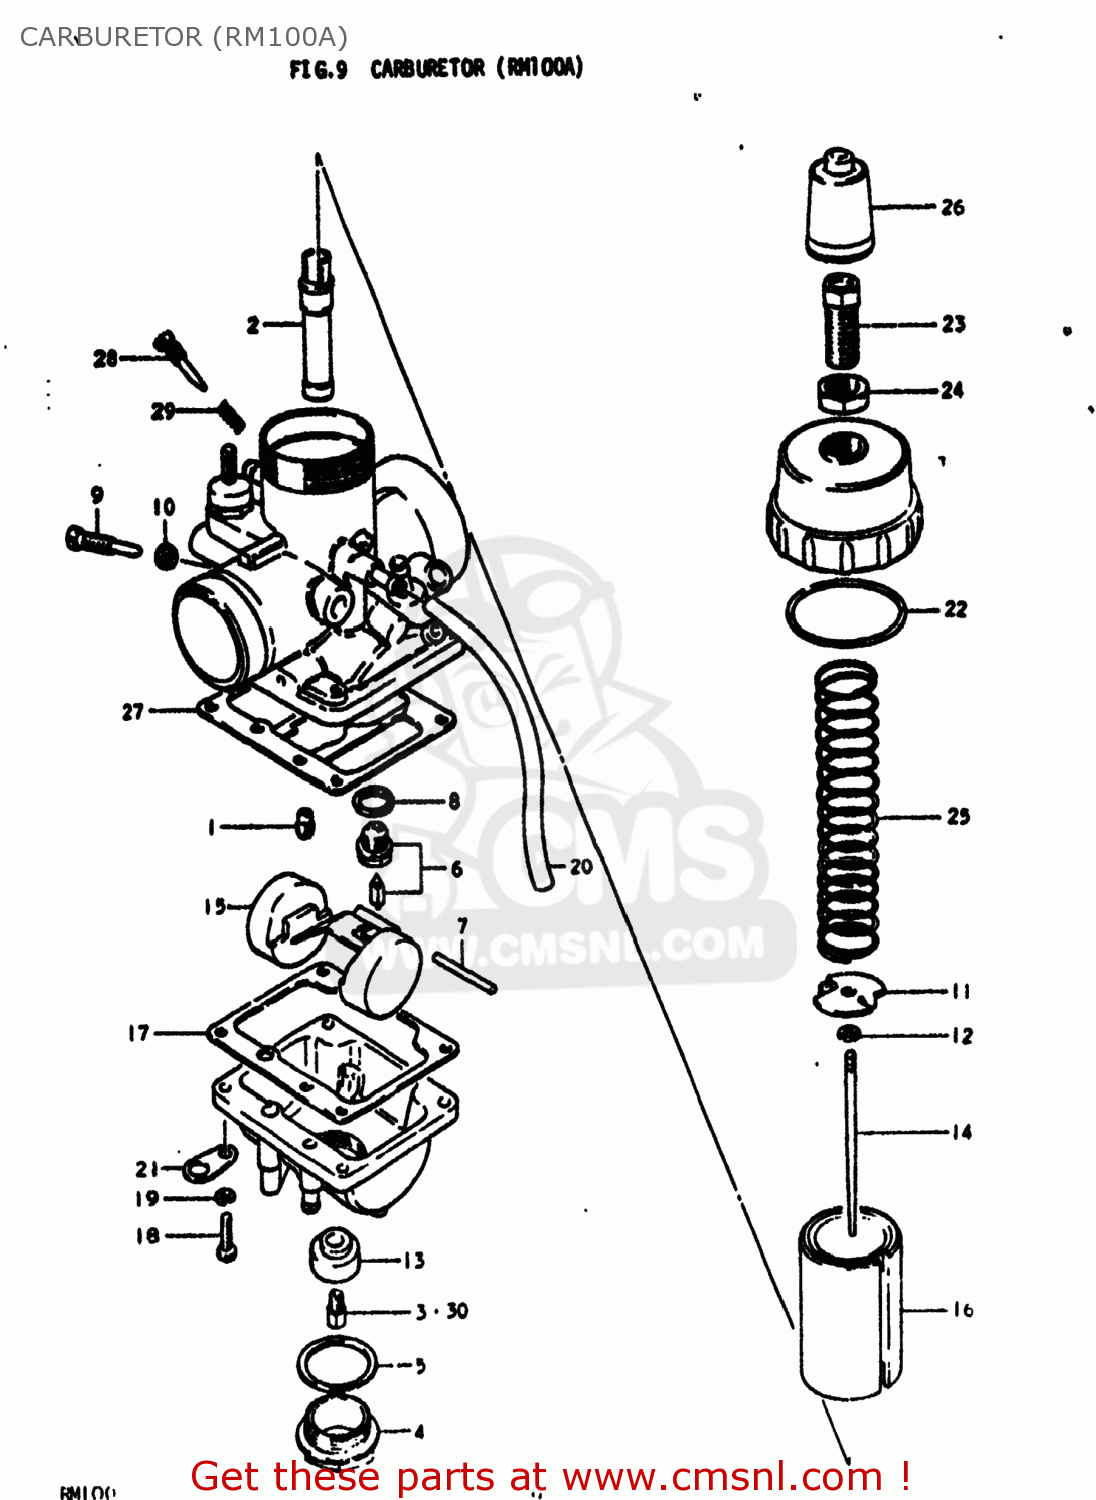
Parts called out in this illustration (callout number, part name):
1	JET,PILOT(35)
2	JET,NEEDLE
3	JET,MAIN(160)
4	PLUG
5	GASKET,DRAIN PLUG (MCA)
6	VALVE ASSEMBLY,NEEDLE
7	PIN,FLOAT
8	GASKET
9	ADJUSTER
10	NUT, STOP SCREW
11	SEAT,THROTTLE VALVE SPRING
12	CLIP
13	RING
14	NEEDLE JET
15	FLOAT
16	VALVE,THROTTLE
17	GASKET,FLOAT CHAMBER
18	SCREW
19	LOCK WASHER
20	HOSE
21	PLATE
22	O-RING
23	ADJUSTER,CABLE
24	NUT,CABLE ADJUSTER LOCK
25	SPRING
26	CAP
27	PLATE
28	SCREW,PILOT AIR
29	SPRING
30	JET
